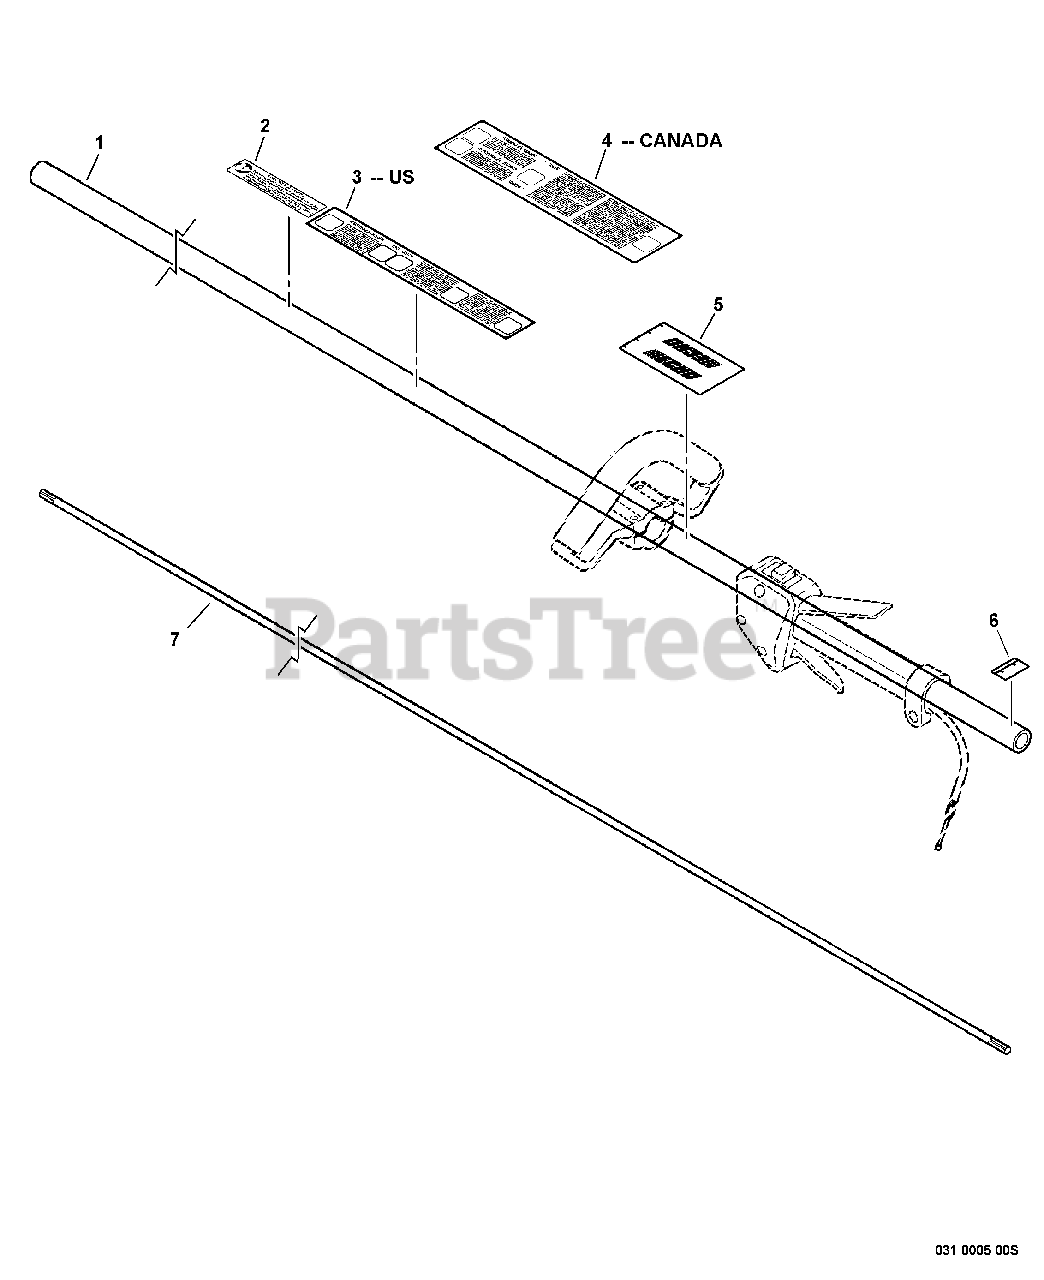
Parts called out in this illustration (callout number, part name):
1	PIPE, MAIN
2	LABEL, CAUTION
3	LABEL, CAUTION
4	LABEL, CAUTION
5	LABEL, HANDLE LOCATION
6	LABEL - ALIGNMENT
7	DRIVESHAFT
